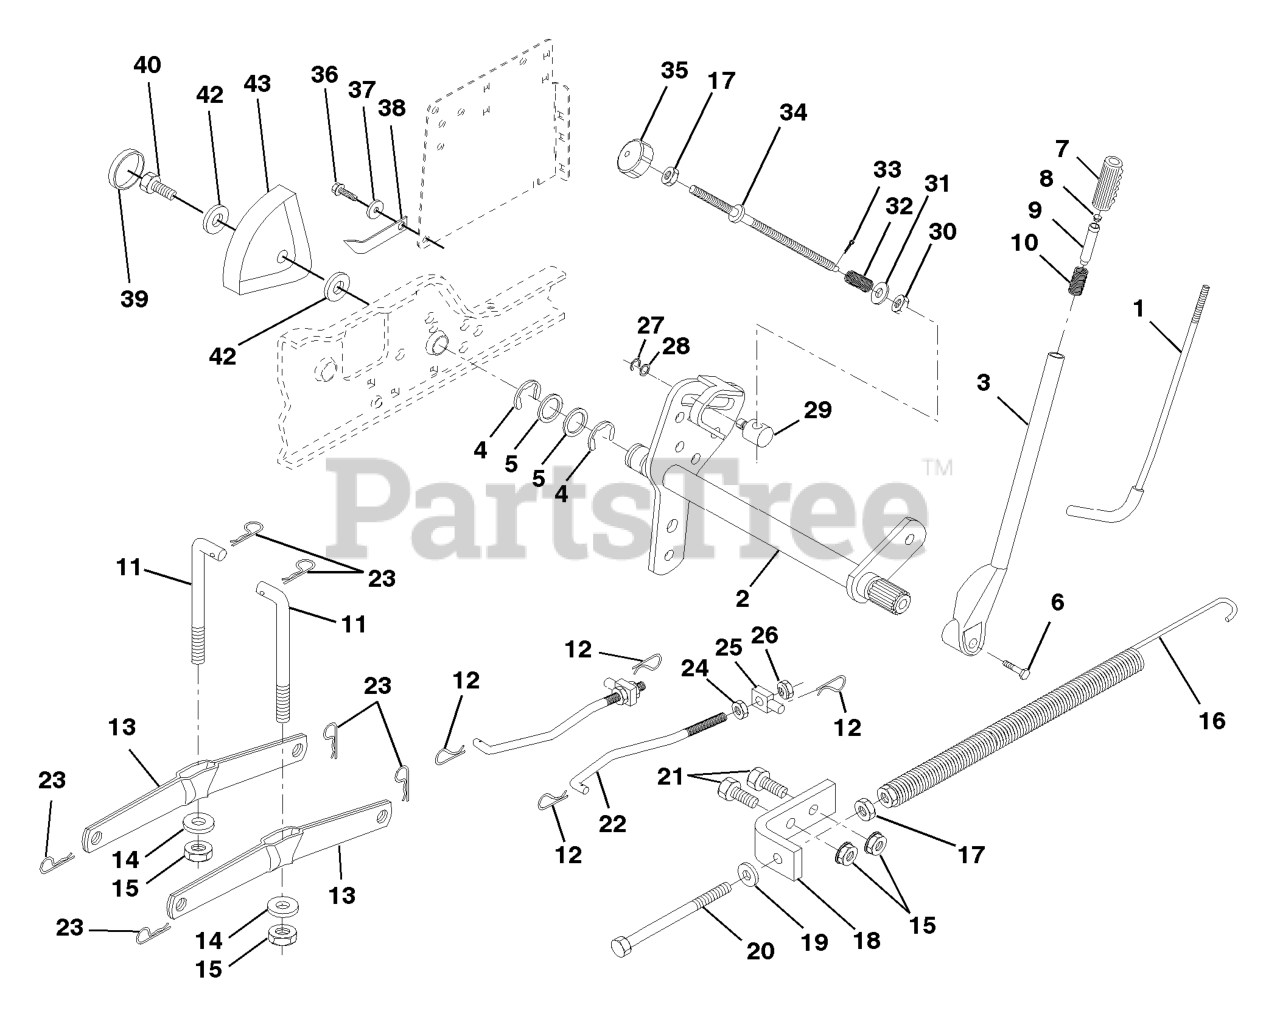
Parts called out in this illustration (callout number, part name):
1	LEVER ROD LT
2	SHAFT ASSY
3	LIFT LEVER KIT
5	Washer 29/32 x 1-1/4 x 16 Ga.
6	BOLT
7	GRIP HANDLE
8	PLUNGER BUT KIT
9	PLUNGER BUT KIT
10	SPRING**
11	LINK LIFT
12	SPRING RETAINER
13	SUSPENSION ARM
14	BEARING PIVOT
15	NUT
16	LIFT SPRING
17	NUT
19	WASHER
21	BOLT
22	FRONT LINK
23	RETAINER-SPRNG RB
24	NUT.HEX.JAM.1/2-13
25	TRUNION
26	NUT.LK.W/WSH.1/2.
27	Ring, Klip #T5304-37
28	Washer 15/32 x 3/4 x 16 Ga.
29	TRUNION LT
32	SPRING.COMP.INF.H
33	COTTER PIN
34	ROD.LIFT.ADJUSTABLE
35	KNOB INF 3/8-16
36	SCREW
38	POINTER HGT
40	SCREW.THDROL.5/16-18X3/4.TTY
43	HEIGHT INDICATOR
